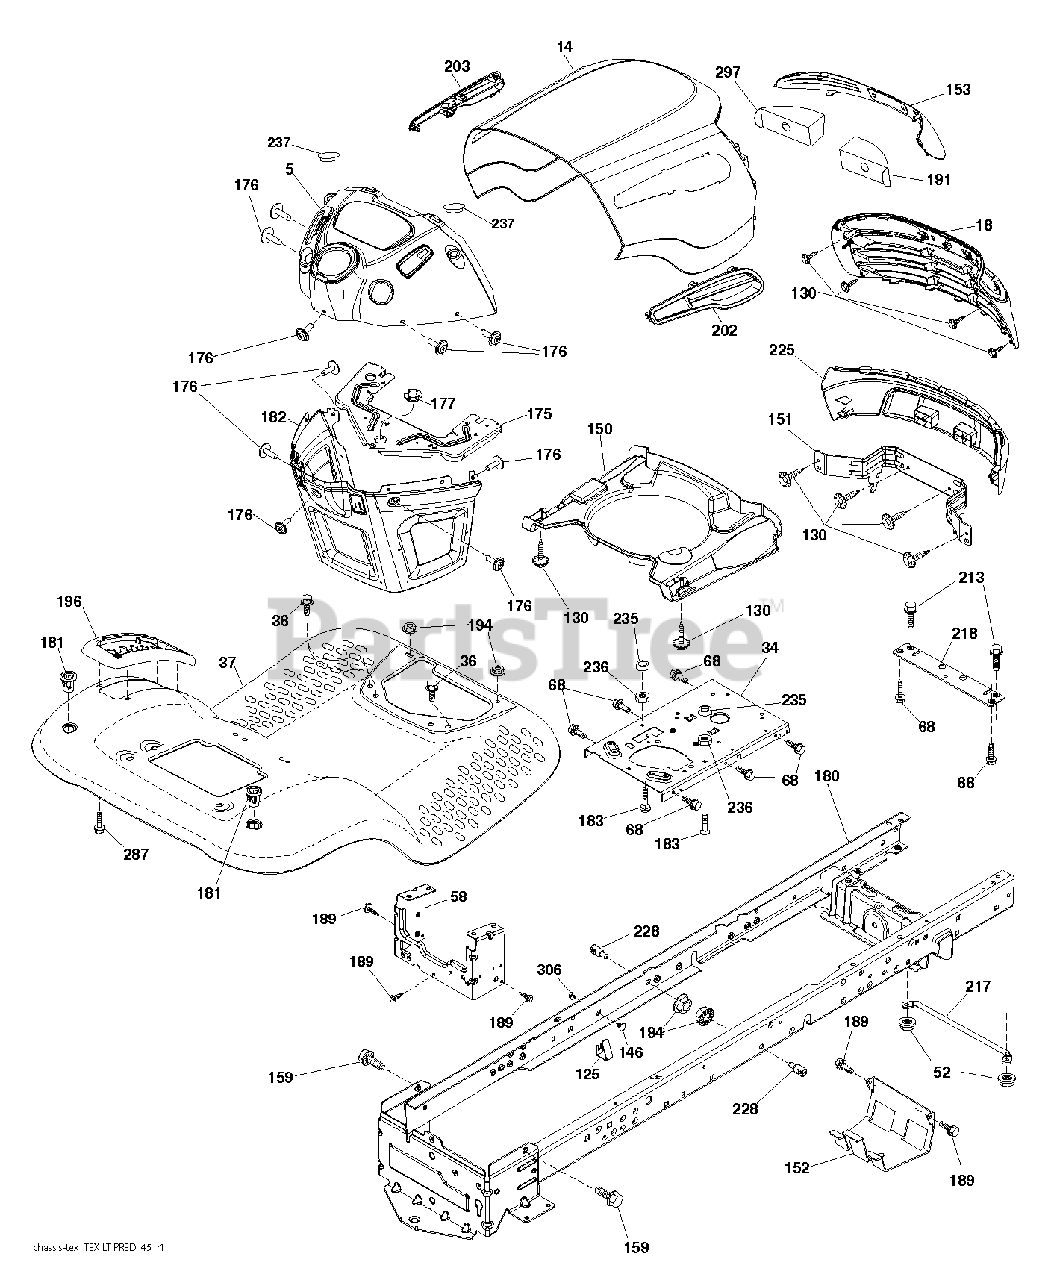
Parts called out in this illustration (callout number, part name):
36	SCREW 5/16"
52	LOCKNUT
58	DRAWBAR UPPER 2PC SMALL FENDER
125	Fuel Line Clip
130	SCREW.#10 X 0.750.BOS THREAD
146	BOLT.RDHD.SHT.SQNK.3
151	BRACKET.PIVOT.ALPHA.LT
152	SHIELD BROWNING
153	LENS.PREDATOR.LT
159	SCREW, 3/8-16X3/4
175	CROSSMEMBER
176	SCREW.#10-24X5/8.RN.QU
177	BUSHING STEERING
180	CHASS.WLDMNT.TL.12GA/2P.48/54
181	FEND/FTRST.PCH.CPH.NFW
182	DASH.LWER.PREDATOR/HUSQ.LT
183	BOLT.5/16-18X1-1/4 FULL THD
189	SCREW
191	INSERT.REFLECT.PREDATOR.LT.RH
194	NUT LOCK HEX FLANGE 5/16-18
196	CONSOLE.ASM.DECKLFT.BL/RBT.TLT
213	BOLT
217	ROD.PIVOT.HOOD
218	X-PIECE.HOOD.STOP.NON/
228	STUD.FASTNER.W/ANTI-ROTATE
235	SPACER FENDER
236	NUT.CENTERLOCK.5/16-
237	PLUG.MOUNT.CARGO.BLK
297	REFLECTOR.INSERT.PRED.LH.LT
306	NUT LOCK FLG 3/8-16 UNC
